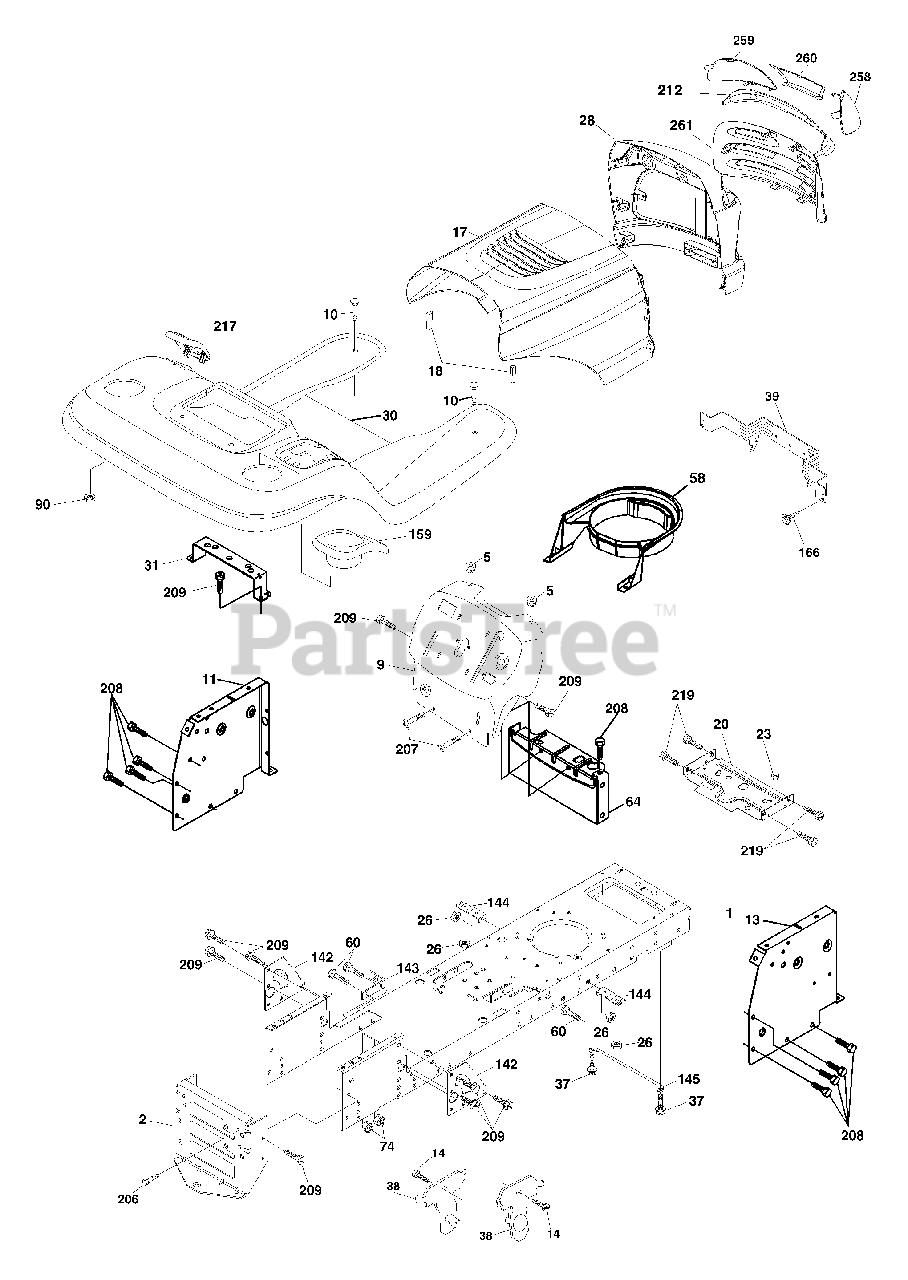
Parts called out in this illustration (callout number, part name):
1	Chassis Stamping
9	Dashboard
10	Bolt Rdhd Sqnk 3/8-16 unc x 1
11	Panel Dash Lh
13	Panel Dash Rh
14	Screw Thdrol 3/8-16 x 1/2
17	Hood
18	Bumper Hood
20	Plate Battery
23	Bushing Snap
26	Nut Lock w/Insert 3/8-16 unc
28	Grille Lens Asm
30	Fender
37	Screw Thdrol 5/16-18 x 1/2
38	Bracket Asm Pivot Mower Rear
39	Bracket Pivot Hood
60	Bolt RDHD SQNK 3/8-16 x 3/4
64	Dash Lower Stlt
74	Nut Crownlock 3/8-16
90	Nut Self-THD Wsh-HD 1/4
142	Plate Reinforcement Stlt
143	Bracket Swaybar Chassis
144	Bracket Ft Rest
145	Rod Pivot Chassis Hood
159	Cupholder
166	Screw Hw Hd Hi-Lo #13-16 x 3/4
206	Bolt Shoulder 5/16-18 TT
207	Screw Thdrol 5/16-18 x 1/2 TYTT
208	Screw Thdrol 3/8-16 x 1/2 Ty-TT
209	Screw 3/8-16 x 3/4
212	Insert Lens Reflect
217	Console Fuel Window
219	Screw 5/16-18 x 3/4
258	Lens RH
259	Lens LH
260	Cover Lens
261	Insert, Grille
